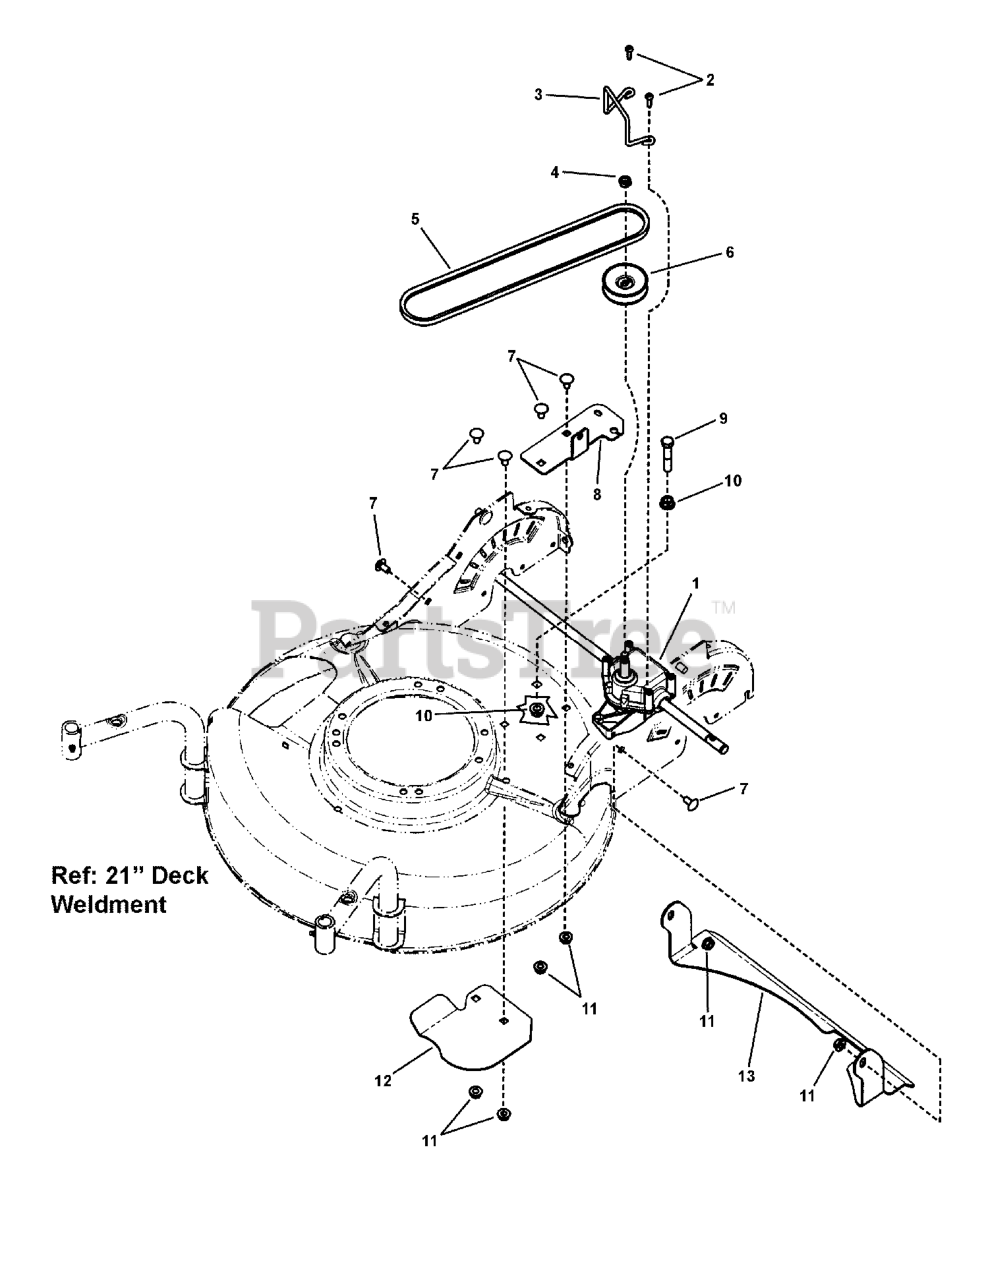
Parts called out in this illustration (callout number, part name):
1	TRANSMISSION, Rocker, 21" WBM
2	SCREW, #10-16 x 3/4", Pan Head Self-Tap (Combo)
3	BELT GUIDE, Transmission
4	NUT, 3/8-16 Hex Center Lock, YZ
5	BELT, 3L, Traction Drive, 21"
6	PULLEY, Transmission, Varaible Speed, LC WBM
7	BOLT, 5/16-18 x 5/8" Round Head Short Square Neck, GR 5
8	BRACKET, Transmission Mounting
9	SCREW, 3/8-16 x 2" Hex Head Cap, GR 5 YZ
10	NUT, 3/8-16 Hex Flange Lock, YZ
11	NUT, 5/16-18 Hex Flange lock, YZ
12	SHIELD, Debris
13	SHIELD, Debris - 21"
